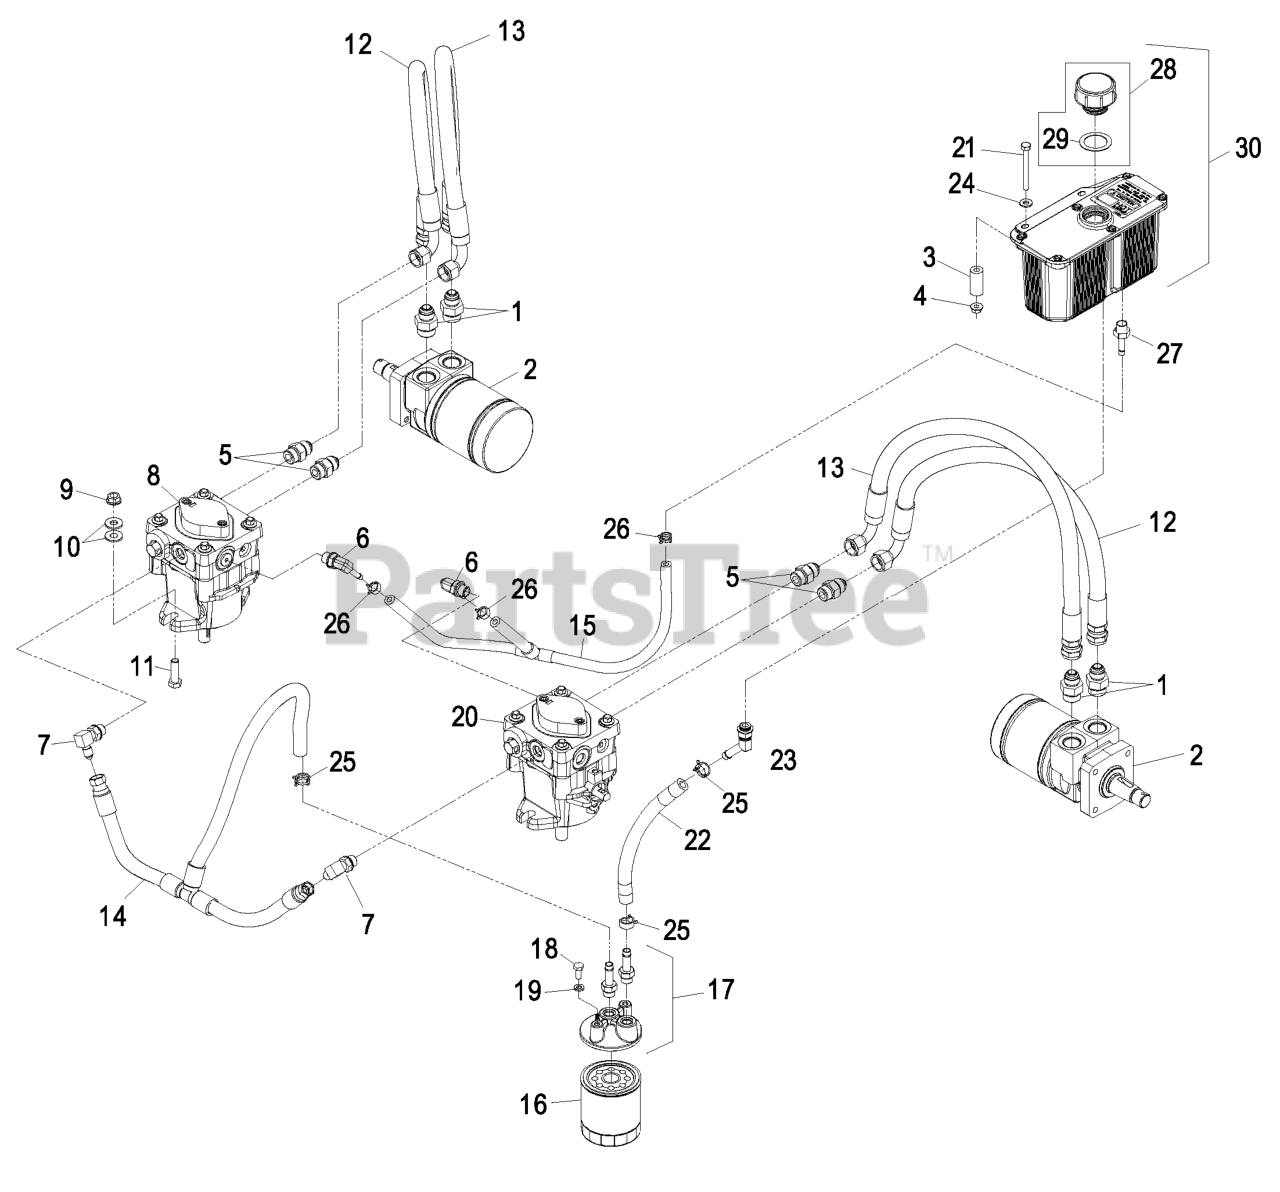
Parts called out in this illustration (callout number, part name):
1	FITTING-STRAIGHT
2	HYD MOTOR ASM
5	FITTING-STRAIGHT
6	ELBOW-90 DEG
7	FITTING-ELBOW, 90 DEG
8	LH HYD PUMP ASM
9	NUT-HHF, WHIZ
10	WASHER-FLAT
11	SCREW-HH
13	HOSE-PRESSURE, HIGH
14	CHARGE HOSE ASM
15	CASE DRAIN HOSE ASM
16	FILTER-25 MICRON, BI-DIRE
17	FILTER HEAD ASM
18	SCREW-HH
19	WASHER-LOCK
20	RH HYD PUMP ASM
21	SCREW-HH
22	HOSE-CHARGE
23	FITTING-BARBED, 45 DEG
24	WASHER-FLAT
25	CLAMP-HOSE
26	CLAMP-HOSE
27	ADAPTER-STRAIGHT
28	KIT,HYD RES CAP W/GASKET
29	GASKET-CAP
30	HYD RESERVOIR ASM
